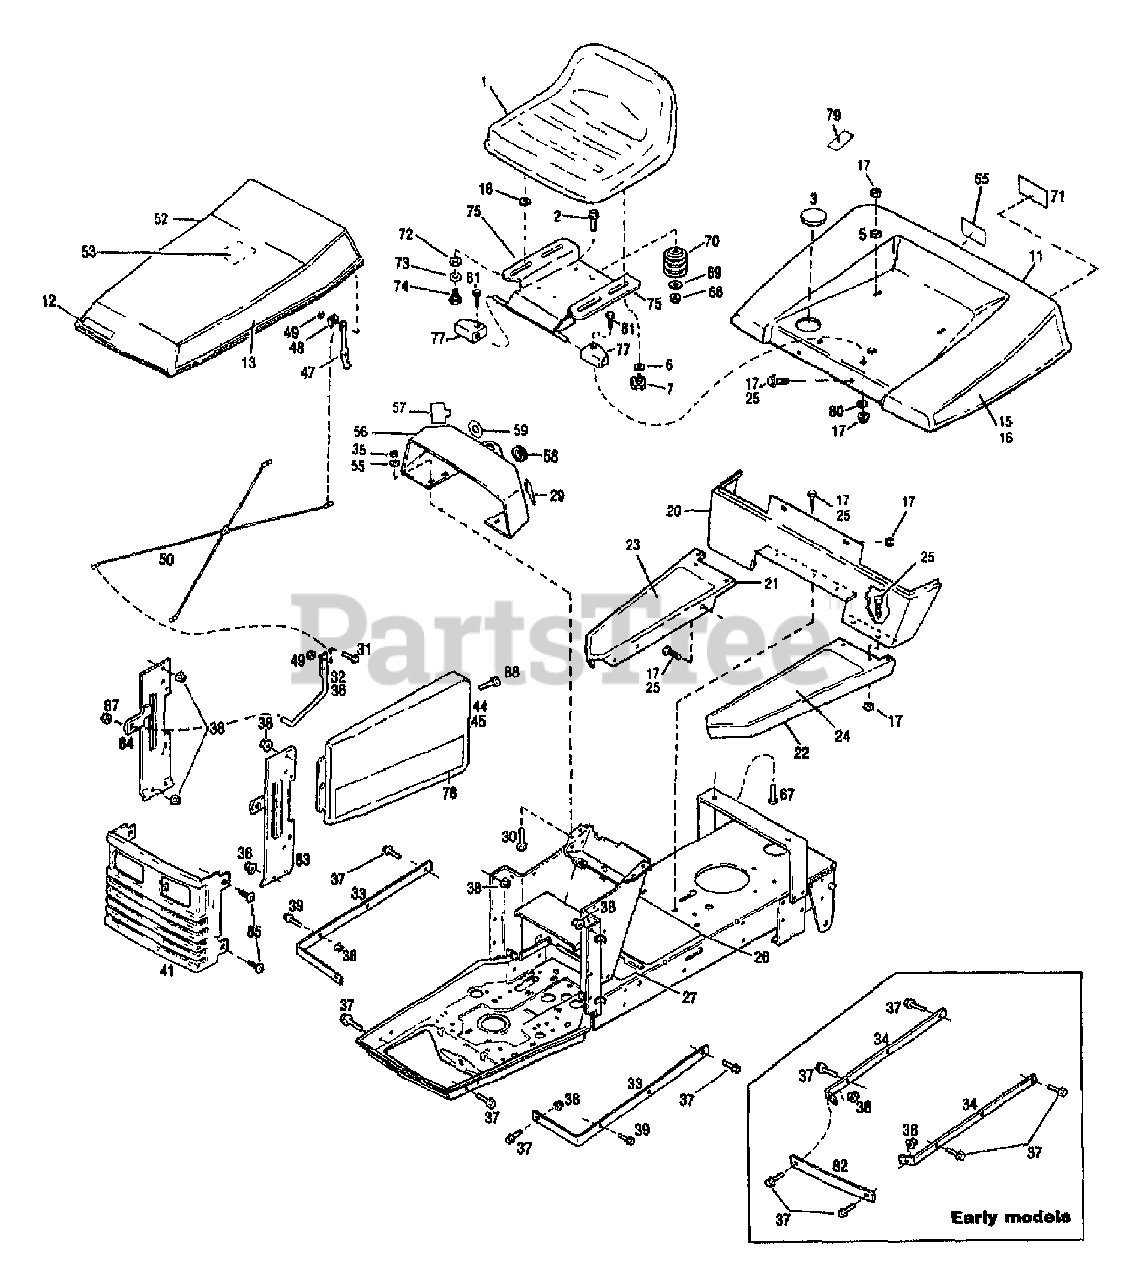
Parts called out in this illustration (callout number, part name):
2	SCR-HFLK 3/8-16X1.00 ZP
5	WASHER-1.25X.343X.059
6	WASHER-FLAT 3/8 SAE
11	FENDER-REAR
12	DECAL-LOGO
13	DECAL-LOGO
15	DECAL-FENDER RH RED
16	DECAL-FENDER LH RED
17	NUT-HFLK 5/16-18 ZP
18	WASHER-FLAT
20	SUPT-RUNNING BOARD
21	BOARD-RUNNING RH
22	BOARD-RUNNING LH
23	PAD-FOOT RH
24	PAD-FOOT LH
25	SCR-LOCK
26	PAD-FOOT
27	DECAL-OPERATING INST
29	DECAL-CHOKE
30	SCR-HH 1/4-20X.625 G5 ZP
32	LINK-HINGE RH
33	ASSM-HINGE STRAP
34	ASSM-HINGE STRAP
35	NUT-HT/LK 1/4-20
36	LINK-HINGE LH
37	SCR-HH 1/4-20X.625
38	NUT-HF/LK 1/4-20 ZP
39	SCR-HFLK 1/4-20X.50 ZP
44	COVER-SIDE LH
45	COVER-SIDE RH
47	LATCH-RUBBER
49	NUT W/LKWASHER 10-24 ZP
50	SUPPORT-HOOD ROD
52	ASSM-HOOD
53	DECAL-SVC INST
55	WASHER-FLAT 1/4 SAE
56	PANEL-INSTRUCTION
57	DECAL-THROTTLE
59	DECAL-IGNITION
65	DECAL-FUEL
67	SCR-CARR 5/16-18X.75
68	NUT-HFLK 3/8-16 ZP
69	WASHER-FLAT 1.25X.406X.179
70	SPRING-COMPRESSION
71	DECAL-LOGO FENDER
72	WASHER-BOW .74X.52X.01
73	WASHER-1.06X.51X.09 NYLON
74	SCR-SHLDR 3/8-16X.25 G5ZP
75	ASSM-SEAT SUPPORT
77	BLOCK-PIVOT
78	DECAL-SIDECVR LH RED
78	DECAL-SIDECVR RH RED
79	DECAL-U.S.A.
80	WASHER-1.5X.343X.104
81	SCR-HH 5/16-18X1.5 G5 ZP
83	ASSM-SUPPORT LH
84	ASSM-SUPPORT RH
87	NUT-SPECIAL
88	SCR-TRUSS #10-24 X 5/8
